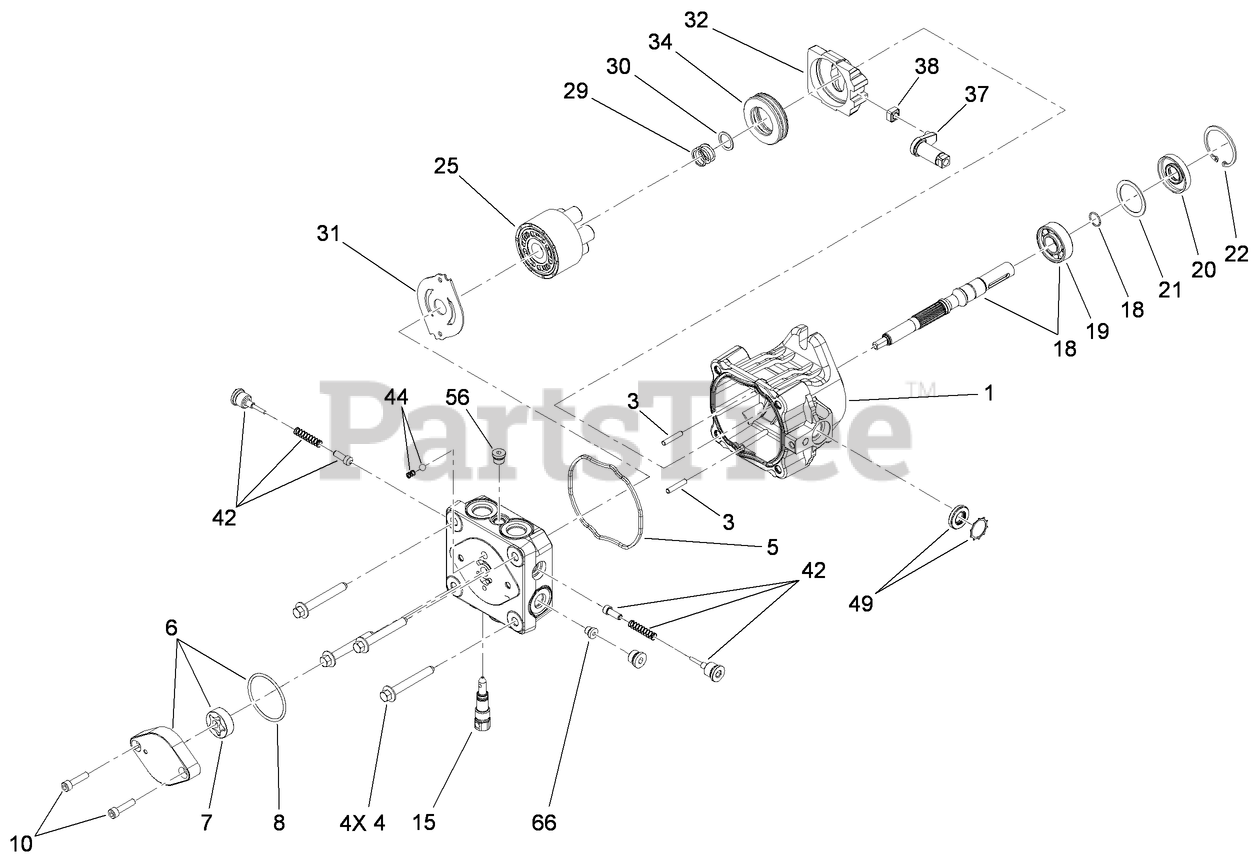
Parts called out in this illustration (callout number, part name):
1	HOUSING KIT
3	PIN-HEADLESS, STRAIGHT
4	BOLT-HF
5	O-RING
6	CHARGE PUMP KIT
7	GEROTOR ASM
8	O-RING
10	CAPSCREW
15	BYPASS VALVE KIT
18	INPUT SHAFT KIT
19	BEARING-BALL
20	SEAL-LIP
21	SPACER
22	RING-RETAINING
25	CYLINDER BLOCK KIT
29	SPRING-BLOCK
30	WASHER-THRUST
31	Plate-Valve
32	SWASHPLATE-VARIABLE
34	BEARING-THRUST
37	ARM-TRUNNION, TAPERED SQUARE
38	GUIDE-SLOT
42	VALVE-CHECK (W/POPPET)
44	CHARGE RELIEF VALVE KIT
49	TRUNNION SEAL KIT
56	PLUG-HSH
66	PLUG-HSH
